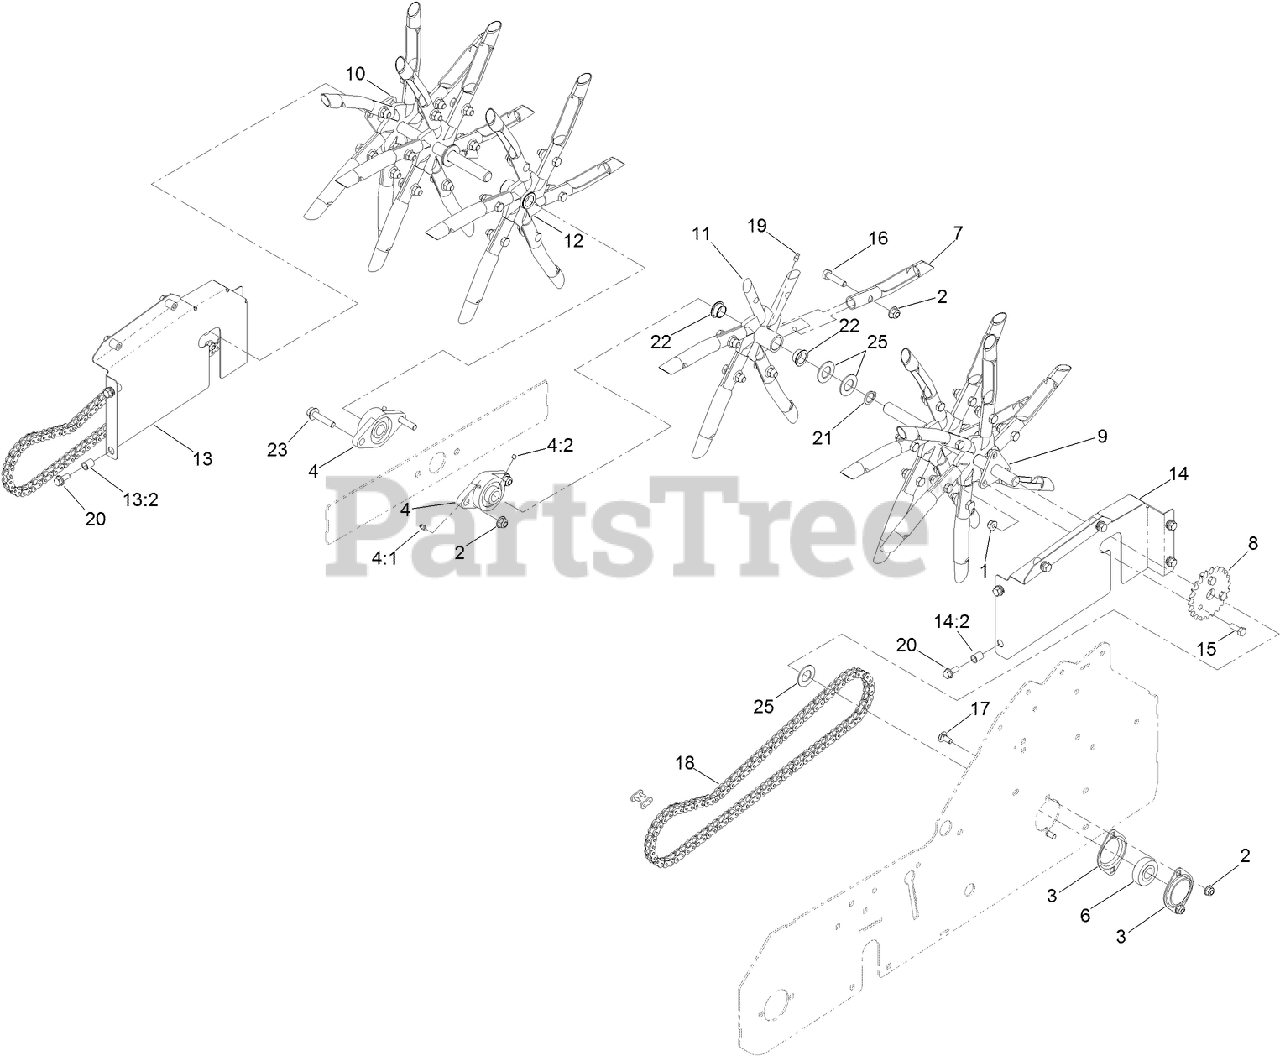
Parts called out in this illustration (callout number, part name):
1	NUT-HF, NI
2	NUT-HF, NI
3	FLANGE-BEARING
4	BEARING-FLANGE
4:1	FITTING-STRAIGHT
4:2	SCREW-SET, HSH
6	BEARING-LOCK, COLLAR
7	TINE-CORING (3/4 INCH)
8	SPROCKET-#40 22T
9	WHEEL-TINE, LH
10	WHEEL-TINE, RH
11	TINE-SPYDER
12	TINE-SPYDER
13	RH CHAIN GUARD ASM
13:2	NUT-CLINCH
14	LH CHAIN GUARD ASM
14:2	NUT-CLINCH
15	SCREW-HH
16	SCREW-HH
17	BOLT-CARR
18	CHAIN-DRIVE
19	FITTING-GREASE
20	SCREW-HHF
21	RING-RETAINING
22	BUSHING-BRONZE
23	SCREW-HHF
25	WASHER
